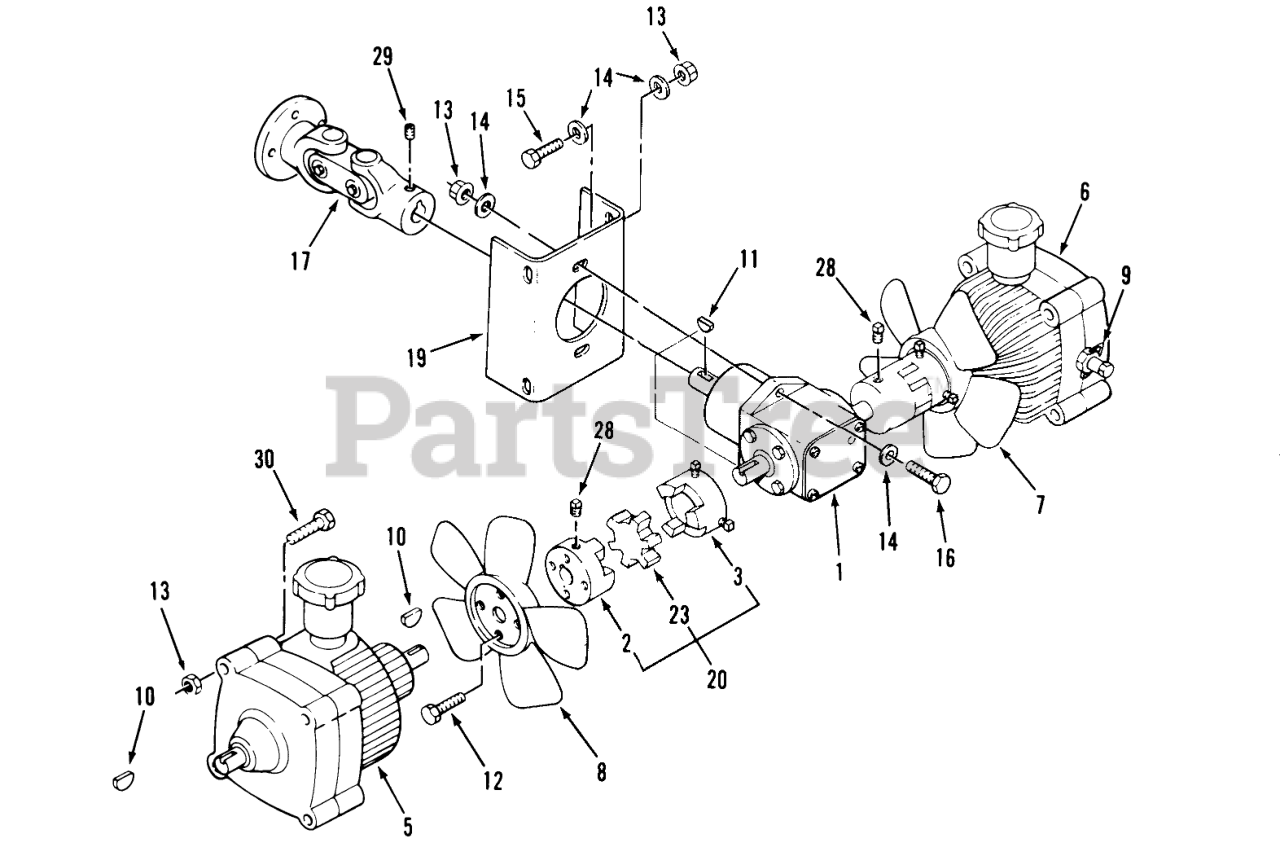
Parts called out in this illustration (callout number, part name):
1	GEAR BOX-T
2	COUPLING-KEYED
3	COUPLING-KEYED
5	TRANS-HYDRO CCW.
6	TRANS-HYDRO CW
7	BLADE-FAN L.H.
8	BLADE-FAN R.H.
9	CLIP-DUMP VALVE
10	KEY-HIPRO
11	KEY-HI-PRO
12	SCREW-TAPTITE
13	NUT-LOCK, NI
14	WASHER-FLAT
15	SCREW-HH
16	SCREW-HH
17	U-JOINT ASSY W/FLANGE
19	BRACKET-GEAR BOX B
20	Coupler-Complete (Incl. Items 2, 3, & 23)
23	SPIDER-COUPLING
28	1/2X1 CUP PT SETSCREW
29	SCREW-SET
30	SCREW-HH
